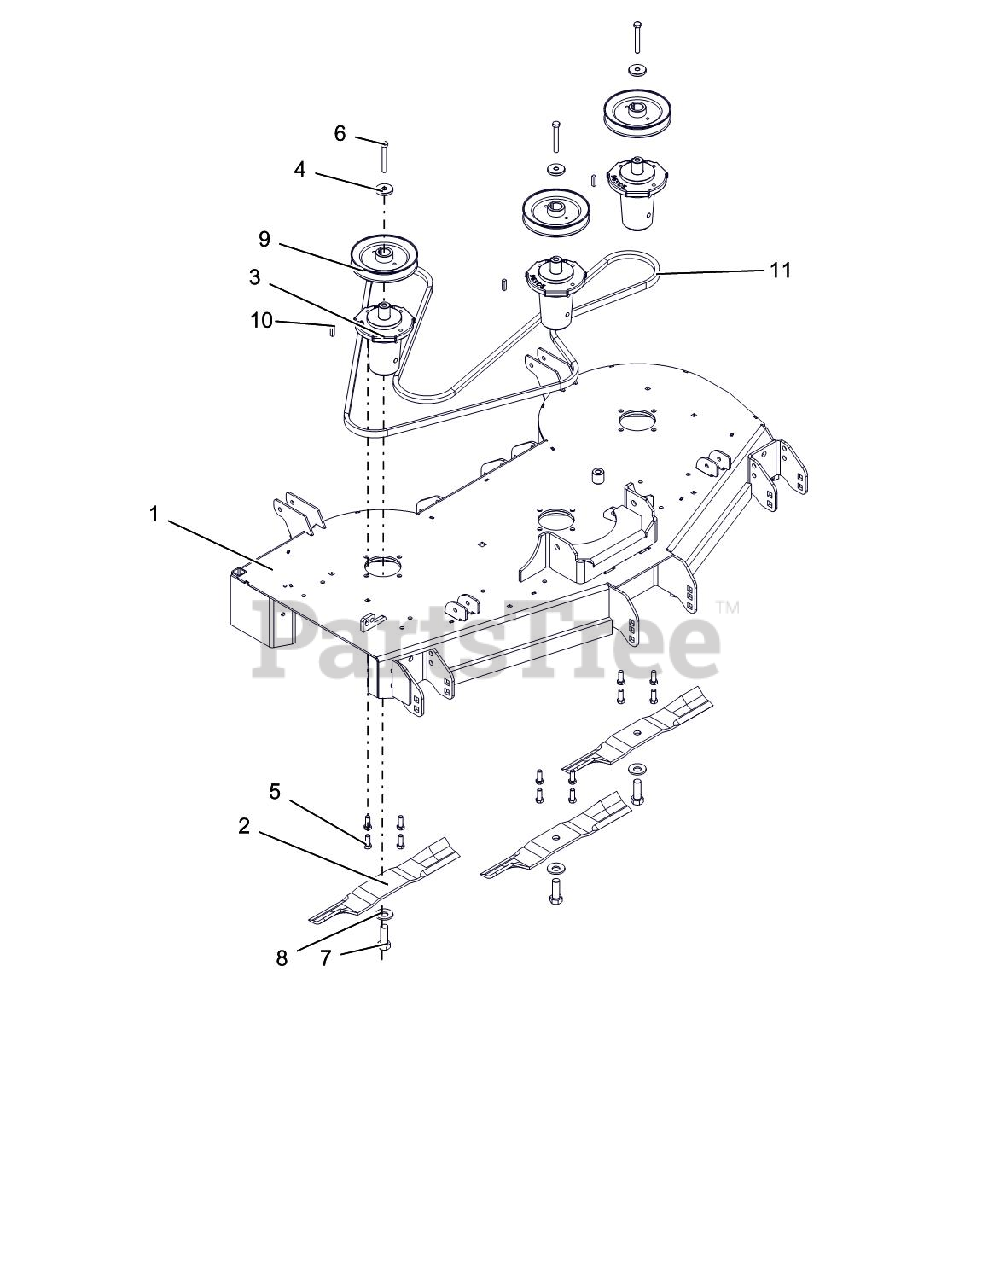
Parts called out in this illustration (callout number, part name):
1	KIT, 48" MOWER DECK W DECALS
2	BLADE, 16.19" MOWER (HI-LIFT)
3	ASM, MAINT FREE SPINDLE
4	RETAINER, SHEAVE
5	BLT-HEX .38-16X1.0 GR8 YZ EP30
6	BLT-HEX .38-16X2.75 GR8 YWZC
7	BLT-HEX .62-18X1.75 GR8 YWZC
8	WSHR-BLVL .669X1.535X.138
9	PULLEY, 1.00 ID X 5.75 OD
10	KEY, SQ .25X.25X1.00 RC 40-50
11	BELT, B-SECTI0N EPDM RAW EDGE
